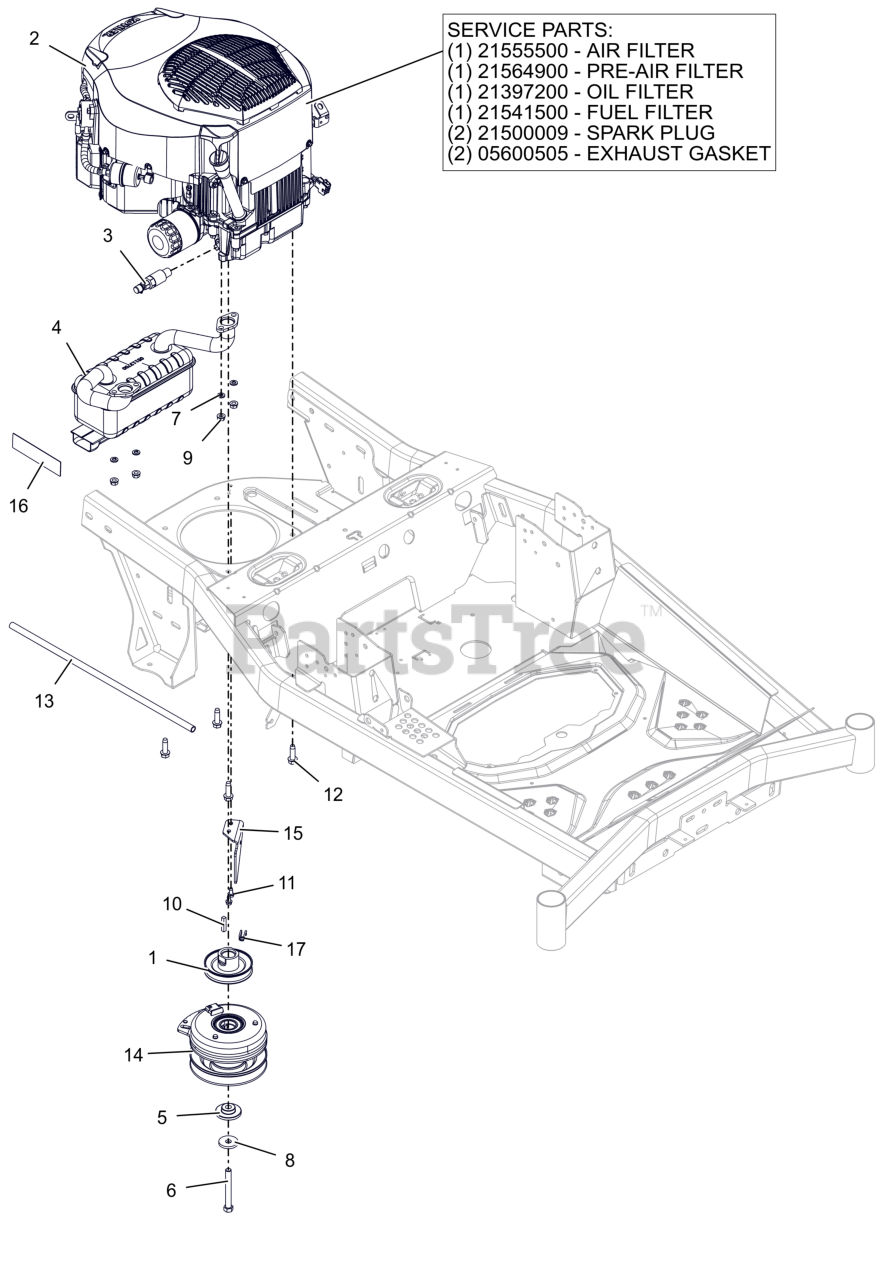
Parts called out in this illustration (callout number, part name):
1	WLDMT, PULLEY 3.75 OD X 1.003 ENGINE
2	ENGINE, KOHLER - KT730
2	AIR CLEANER, KOHLER
2	PRE-CLEANER, KOHLER
2	FILTER, OIL - KOH CV20
2	FILTER, FUEL
2	PLUG, SPARK KOHLER
2	GASKET, MUFFLER COURAGE TWIN
3	DRAIN, OIL
4	MUFFLER, KOHLER
5	BSHG-FLG .469X1.06X.574X2.0
6	BLT, HEX 0.4375-20X3.5 G8 ZCC NT
7	WSHR,LK-REG .312X.078 ZCC
8	WASHER, 7/16" SPRING DISK
9	NUT-LK-TOP-FLG .312-18 GF ZCC
10	KEY-SQ .25 X 1.25 X .25 SAE
11	SCR-TAP .25-20X.50 HWH ZCC
12	SCR,TAP .375-16X1.25HWH TR ZCC
13	HOSE, OIL DRAIN
14	CLUTCH- WARNER IXR-18211
15	BRKT- CLUTCH STOP
16	TAPE- HEAT DEFLECTOR
17	BSHG, CLUTCH
